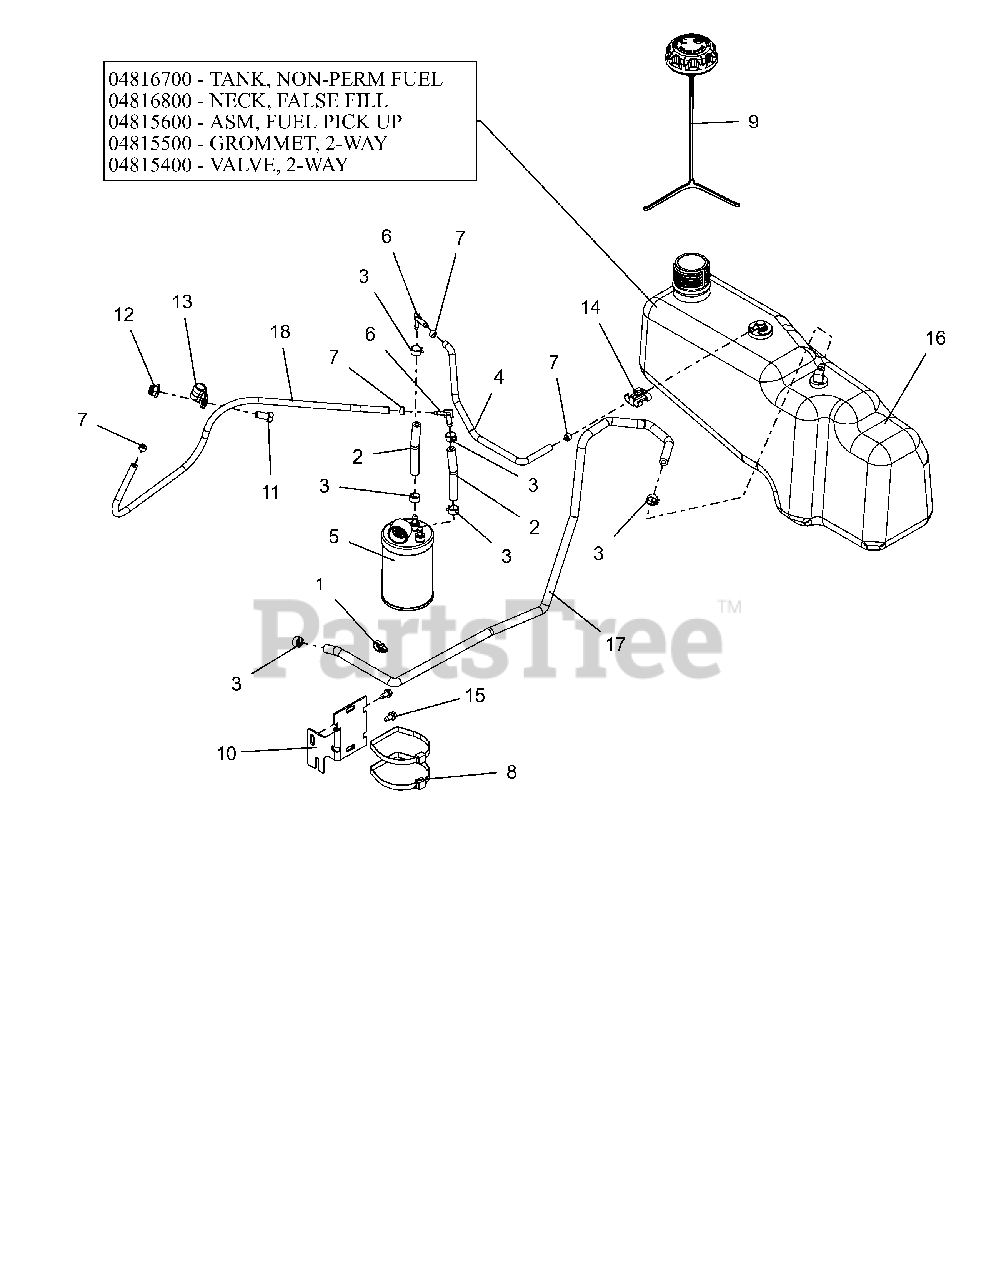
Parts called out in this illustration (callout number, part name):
1	ROUTING CLIP (1/2" ID)
2	HOSE, .25 LOW-PERM BULK GAS
3	CLAMP, FUEL LINE
4	HOSE, .188 LOW-PERM BULK GAS
5	CARBON CANISTER, 300CC
6	FITTING-3/16X1/4 90DEGREE VAC
7	CLAMP-HOSE, SPRING .188
8	P-PLASTIC TIE STRAP LARGE
9	CAP, FUEL VENT-IN 2.25" RATCH.
10	BRKT, CARB CANISTER MOUNT
11	@BLT-HEX .38-16X.75 GR5 YWZC
12	@NUT-LK-NYL-FLG .38-16 YWZC
13	CLAMP, CUSHIONED STEEL
14	CLIP, T, .38-.50
15	SCR-TAP .25-20X.50 HWH TR YWZ
16	ASM,TANK NON-PERM FUEL
16	TANK, ZOOM/ZT NON-PERM, FUEL
16	NECK, FALSE FILL ZOOM/ZT
16	ASM, FUEL PICK-UP ZOOM/ZT 2015
16	GROMMET, 2-WAY
16	VALVE, 2-WAY
17	HOSE, .25 LOW-PERM BULK GAS
18	HOSE, .188 LOW-PERM BULK GAS
